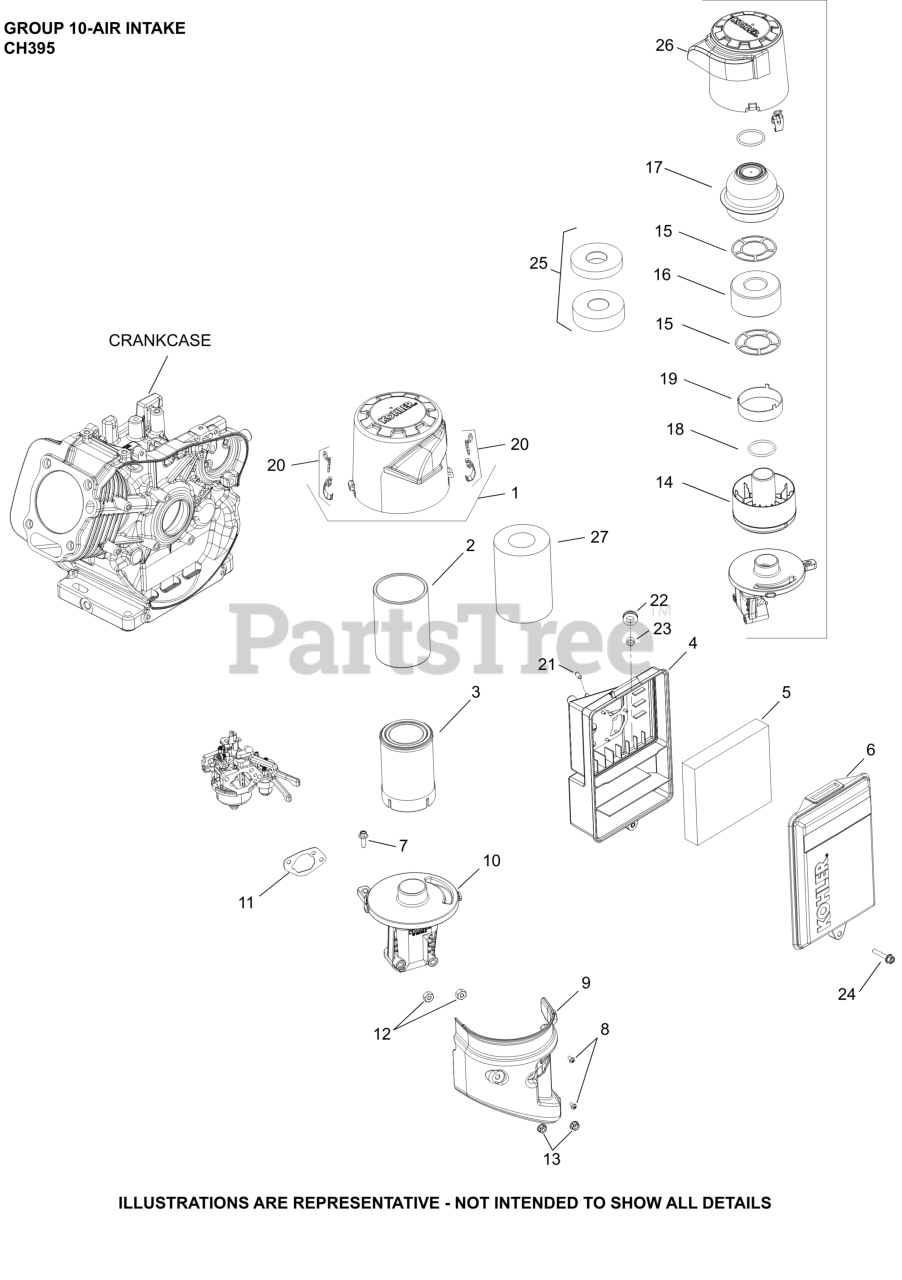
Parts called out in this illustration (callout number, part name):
3	NUT, HEX FLANGE LOCK (M6)
4	BASE ASSEMBLY, AIR CLEANER
5	ELEMENT, AIR FILTER
6	COVER, AIR CLEANER
11	GASKET, AIR CLEANER
21	CAP, MASKING (CKY)
22	ISOLATOR, VIBRATION
